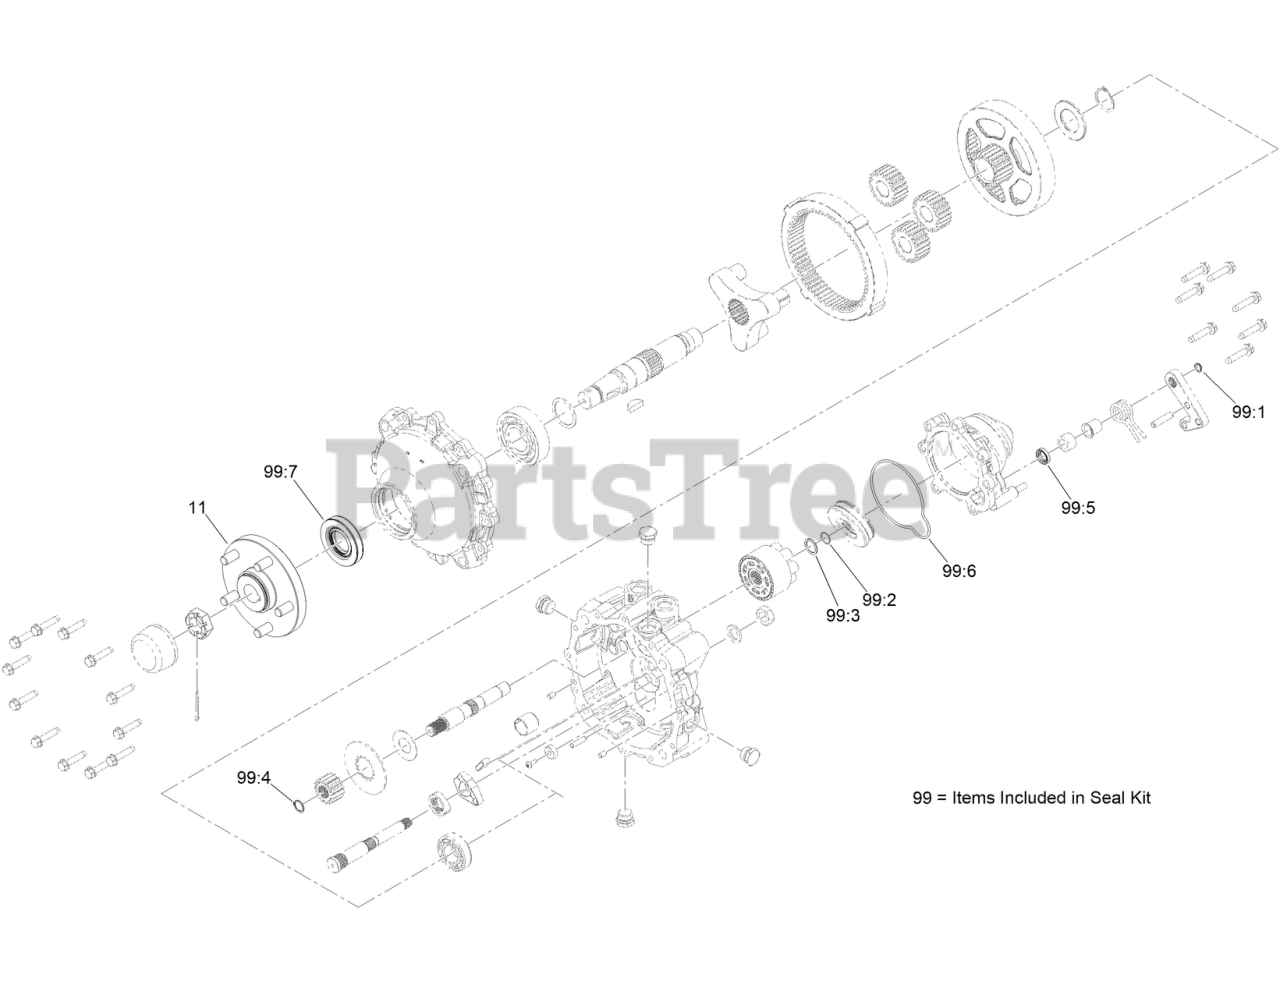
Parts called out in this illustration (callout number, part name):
11	5 STUD WHEEL HUB KIT
99	SEAL KIT
99:1	RETAINER RING
99:2	RING-RETAINING
99:3	WASHER
99:4	RING-RETAINING
99:5	SEAL, BRAKE
99:6	O-RING, ROUND
99:7	SEAL, AXLE
